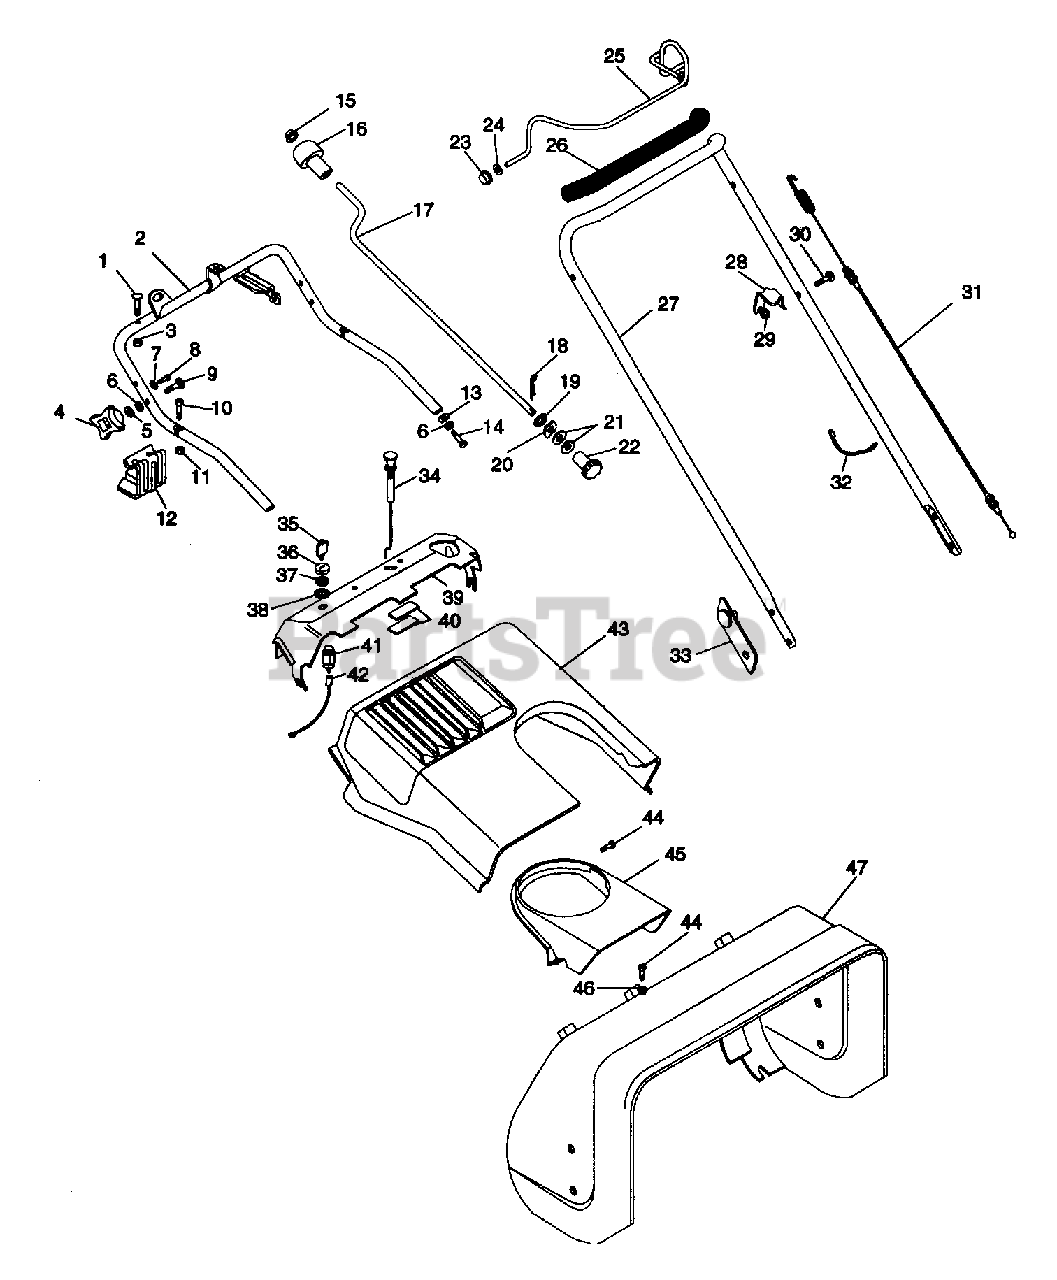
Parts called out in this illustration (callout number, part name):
1	BLT-CRVD-HD .25-20X.25 PL
2	TUBE WELDMENT
3	NUT-LK-FLG .250-20 PL
4	KNOB 5/16-18 UNC
5	WSHR-FL-STL .323X.625X.062 PL
6	WSHR-LK .312X.097 PL HVY
7	WSHR-FL-STL .281X1.250X.048PL
8	SCR-TAP #10-16 X .625 HWH
9	BLT-RDHDSQNK.31-18X2.25 PL
10	SCR-SKH .25-20X1.25 FLTCNTRSK
11	NUT-LK-CTR .250-20 PL
12	SWITCH BRACKET WELDMENT
13	WSHR-FL-STL .328X.875X.062 PL
14	BLT-HEX .31-18X1.25 PL GR2
15	CAP, 3/8 ROD YWZC
17	CHUTE CRANK
18	PIN-HAIR INT .08X.38X1.42 YWZC
19	PUSHNUT .625
20	WAVE WASHER .640X.875X.125FH
21	WSHR-FL-STL .630X1.005X.062 PL
23	NUT-PUSH .312 DIA. PAL
24	WSHR-FL-STL .344X.688X.065 PL
25	BAIL
26	HANDLEBAR CUSHION
27	UPPER HANDLEBAR
28	CABLE ANCHOR-LH
29	NUT-LK-FLG .250-20 PL BLK
30	BLT-RDHDSQNK .25-20X1.25 XLGPL
31	CONTROL CABLE
32	CABLE TIE LG 5-1/2
33	STRAP ASSEMBLY
34	CHOKE CONTROL
35	KEY -W/CAP
36	CAP - IGNITION SWITCH
37	NUT-PANEL .625-32 GRECO
38	WSHR-LK-INT .625X.045 PL
39	DASH W/DECAL
40	CATCH ASSEMBLY
41	KEY SWITCH ASSEMBLY
43	ENGINE COVER
44	SCR-TAP 10-24X.50 CRTRH PL AB2
46	PLASTIC GROMMET
47	AUGER COVER W/DECALS
